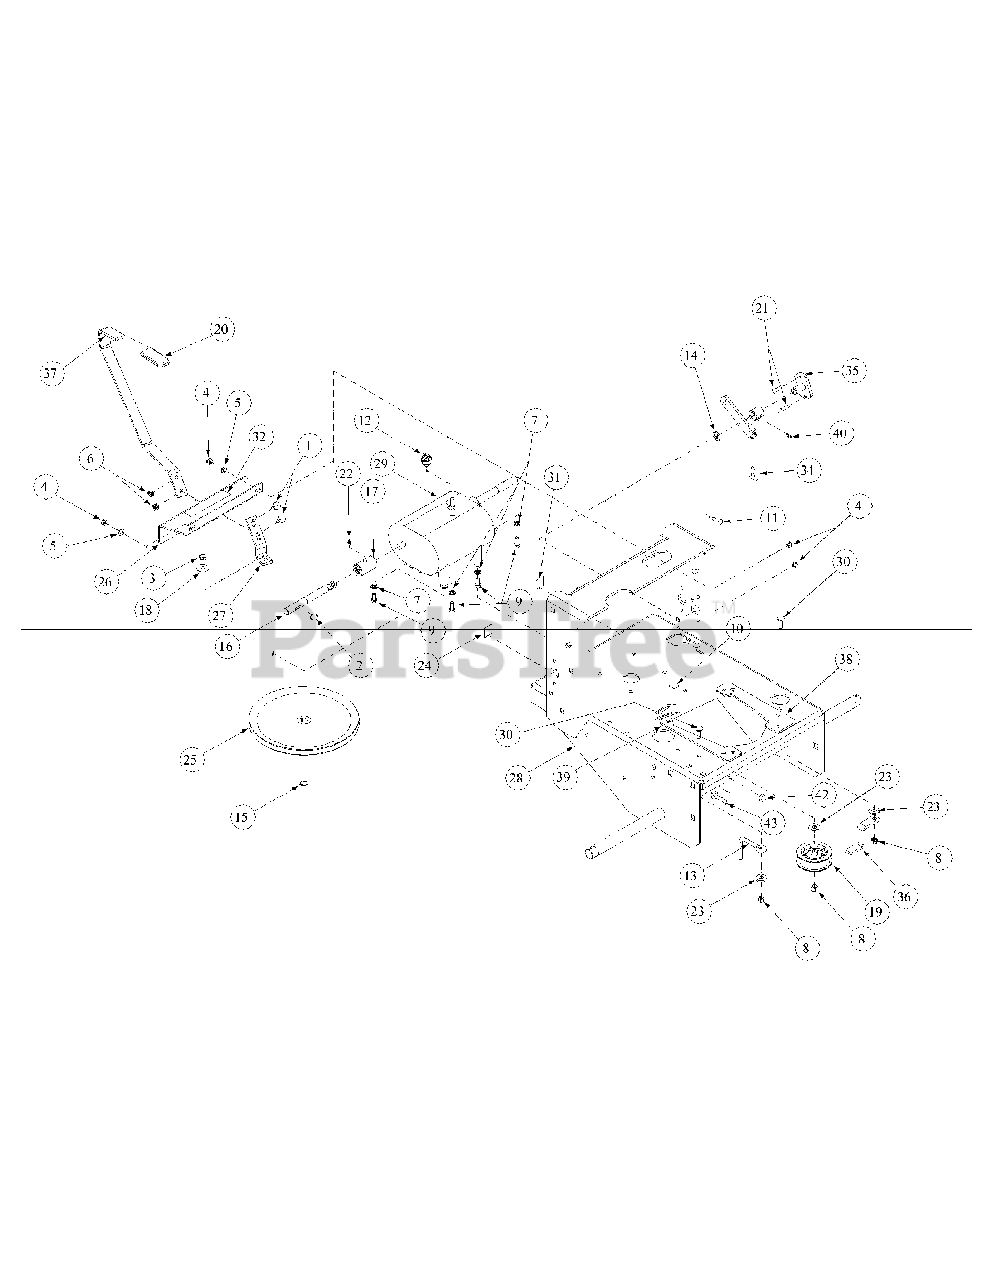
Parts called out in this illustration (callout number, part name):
1	Carriage Bolt, 5/16-18 x 1
2	Woodruff Key, 3/16 x 3/4
3	Jam Nut, Insert Lock, 3/8-24
4	Lock Nut, Nylon Insert, 1/4-20
5	Flat Washer, 1/4 Zinc
6	Nut, 5/16-18 Nylock
7	Lock Washer, 5/16 Zinc
8	Lock Nut, Nylon Insert, 3/8-16
9	Hex Cap Screw, 5/16-18 x 3/4
10	Carriage Bolt, 3/8-16 x2
11	Carriage Bolt, 1/4-20 x .750
12	Switch, WB Transmission
13	Drive Belt Guide
14	E-Ring, 5/8
15	External Retainer Ring
16	Jackshaft w/ Heavy Spline
17	Coupling w/Heavy Spline
18	Bell Washer, .39 ID x 1.13 OD x .062
19	Flat Idler Pulley w/Adapter
20	Grip, .250 x 1 x 3-1/2, Yellow
21	Carriage Bolt, 1/4-20 x 1.00
22	Grease Fitting, 1/4-28 x 3/16
23	Idler Washer
24	Decal "Made In America
25	Transmission Pulley
27	Shift Arm
28	Engine Deck Assembly
29	Transmission, 5 Speed
30	Carriage Bolt, 3/8 -16 x 1.25
31	Label, Warning, Open Belt Drive
32	Label, Mower Instruction
34	Clutch, Bellecrank Weldment
35	Bellecrank Pivot, Weldment
36	Engine Belt Guide
38	Engine Spacer, LH
39	Engine Spacer, RH
40	Grease Fitting, 1/4-28 x 3/16
42	Hex Lock Nut, 1/4-20
43	Hex Cap Screw, 1/4-20 x 2
